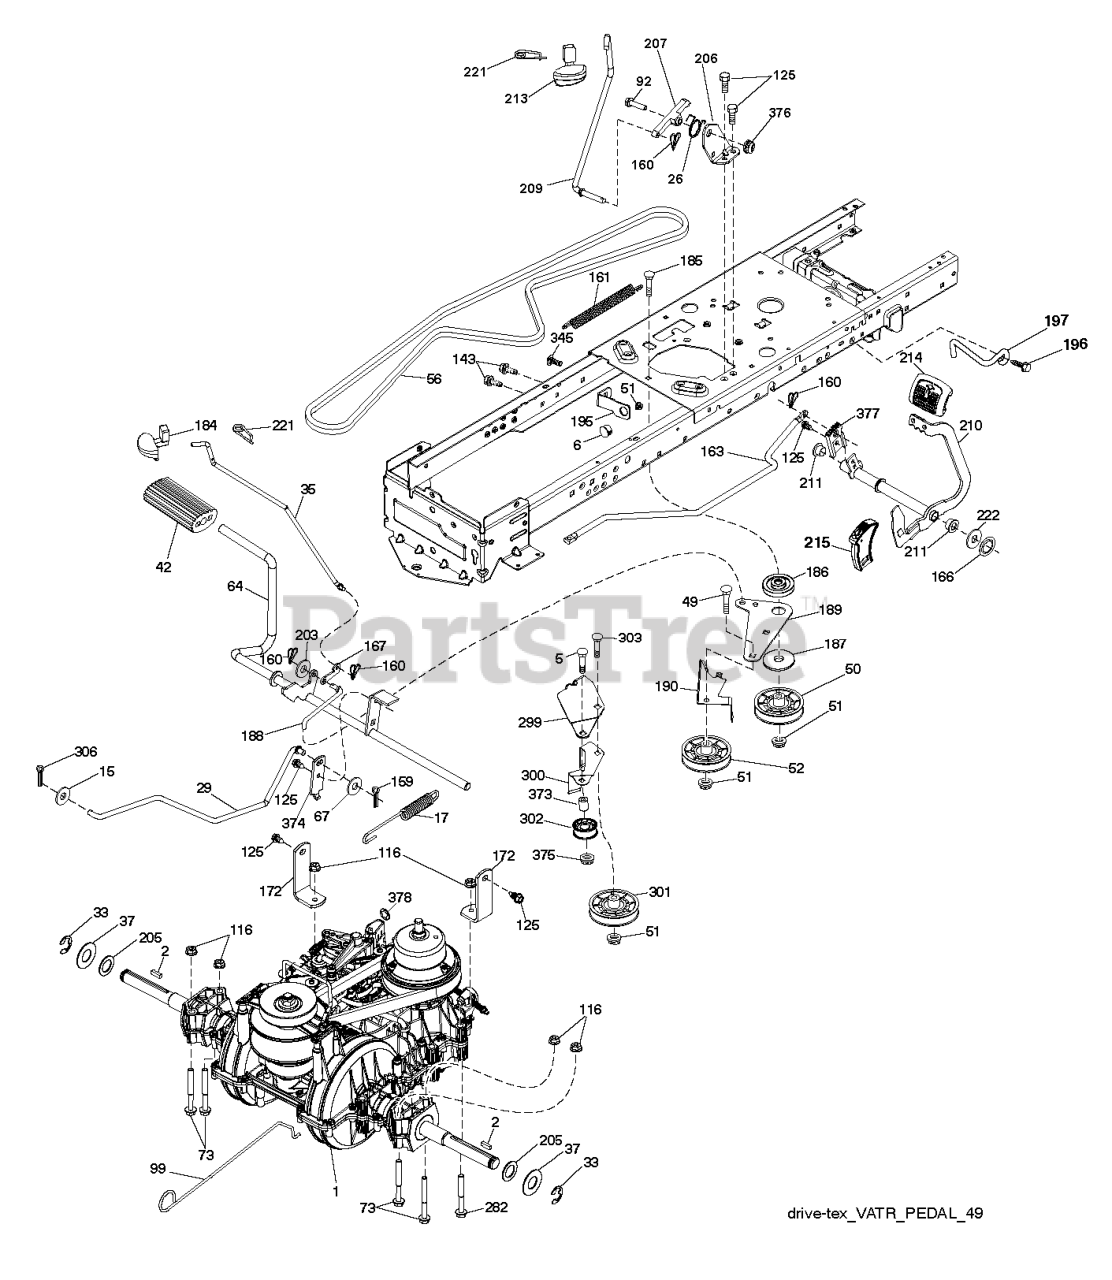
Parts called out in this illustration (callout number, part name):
2	SQUARE KEY
6	BUSHING.SNAP.NYL.BLK.
15	WASHER
17	SPRING BRAKE VARIATOR
26	SPRING.RETURN.CRUISE
29	BRAKE.VARIATOR.SD3
35	ROD .BRAKE. PARKING. GT. HUSQ.
37	WASHER.HARDENED
42	PEDAL COVER T
49	BOLT
50	IDLER.FLAT.910.OFFSET
51	NUT LOCK FLG 3/8-16 UNC
52	IDLER.V-GROOVE.910.OFFSET
56	BELT.DRIVE.MOWER.TEX.42"
64	SUBASM.SHAFT.PEDAL.BRAKE
67	WASHER
73	BOLT HEX 5/16-18 GR 5
92	BOLT
99	ROD.BYPASS.VARIATOR.GEN2
116	NUT LOCK HEX FLANGE 5/16-18
125	SCREW
143	SCREW LT
159	COTTER PIN
160	RETAINER CLIP
161	SPRING, RETURN LT
163	ROD.CONTROL.PEDAL.VARIATOR
166	NUT.PUSH.625
167	LATCH.BRAKE.SPRING
172	STRAP.TORQUE.VARIATOR
184	RB HANDLE.PARKG.BRK.HUS/PRED
186	SPACER.RETAINER
187	WASHER 12/32X2X10GA
188	RP.LINK.CLUTCH.GROUND.DRIVE
189	BELLCRANK.GROUND.DRIVE.TEX.
190	KEEPER.BELLCRANK.DRIVE
195	BRACKET.BRAKE.BRAKE.VAR.SD
196	SCREW 3/8-16X1
197	LINK.CLUTCH.ANIT-ROTAT
203	WASHER
206	BRACKET.MOUNT.CRUISE.LATCH
207	LATCH.CONTROL.CRUISE.VARIATOR
209	ROD.CONTROL.CRUISE.GT.
210	WELDMENT.PEDAL.VARIATOR
211	BEARING.NYLON
213	KNOB.CONTROL.CRUSIE.HU
214	PEDAL.FORWARD.PAD.TEX
215	PEDAL.REVERSE.TEX.GT.4
221	RETAINER.SPRING.CLIP.H
222	WASHER 21/32 X 1-1/4 X 10 GA.
278	BOLT CRUISE VARIATOR
282	BOLT HEX FLGHD 5/16-18X3 GR. 5
299	BRACKET.MOUNT.IDLERS
300	KEEPER.IDLERS.REAR.VARIATOR
301	PULLEY.IDLER.V-GROOVE
302	PULLEY.IDLER.FLAT.2"
303	BOLT CARRIAGE
306	PIN COTTER
345	BOLT
373	SPACER.IDLER
374	ARM.CONTROL.BRAKE
375	LOCKNUT
376	NUT.FLANGE.HEX.5/16X18.BLACK
377	GEAR.SECTOR.CONTROL.CRUISE.VAR
378	NUT.PUSH.8MM
